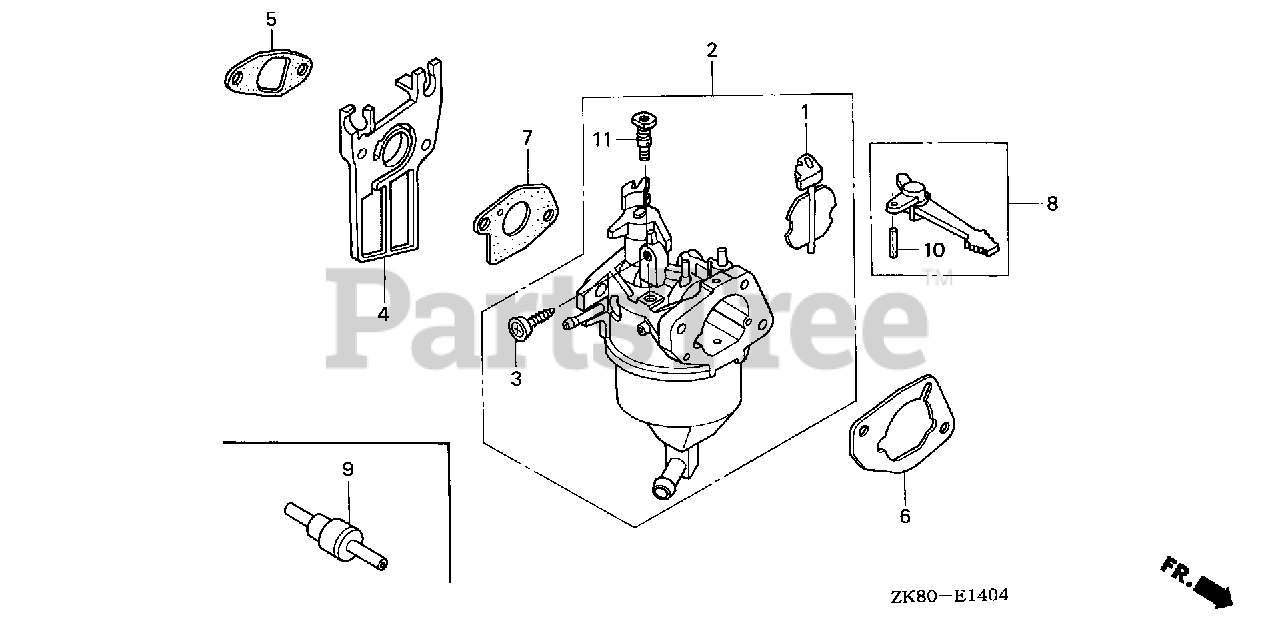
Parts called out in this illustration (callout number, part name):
2	CARBURETOR ASSY. (BEL0A A)
3	SCREW, THROTTLE STOP
4	INSULATOR, CARBURETOR
5	GASKET, INSULATOR
6	SPACER, CARBURETOR
7	GASKET, CARBURETOR
8	LEVER, CHOKE (STD)
9	VALVE, DASHPOT CHECK
10	PIN, SPRING (2X12)
11	JET SET, PILOT (#35)
